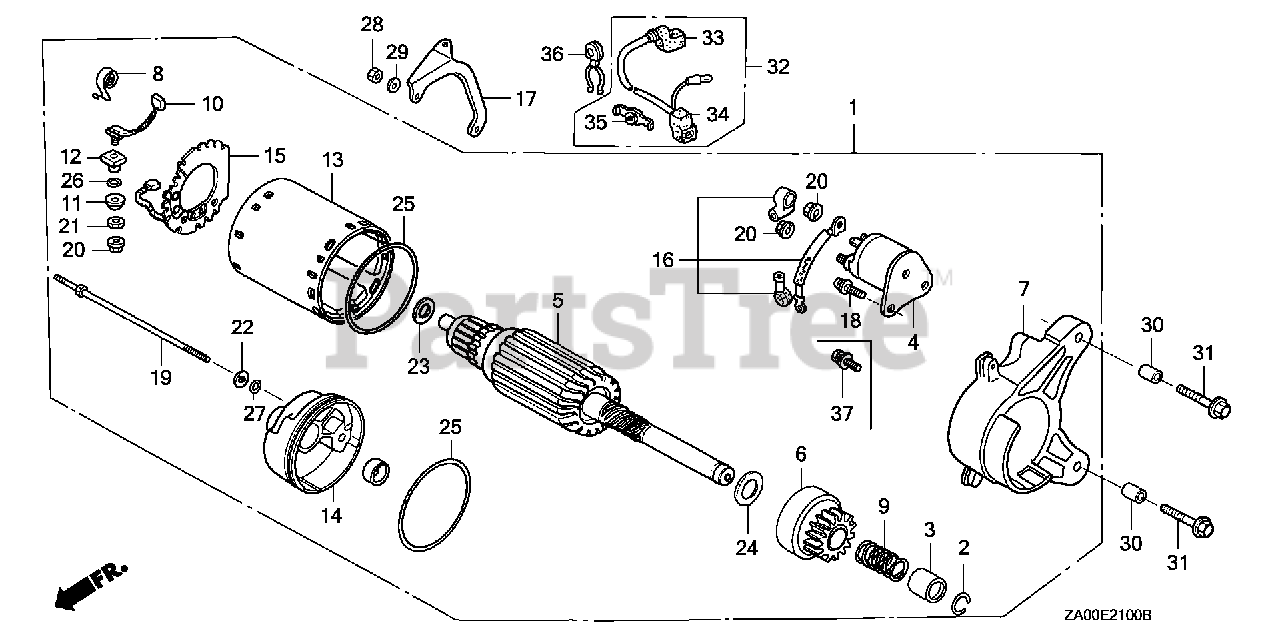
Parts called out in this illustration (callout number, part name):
1	STARTER MOTOR ASSY.
2	RING, SNAP
3	COLLAR, CLUTCH STOP
4	CONTACTOR ASSY.
6	CLUTCH ASSY., OVERRUNNING
7	HOUSING, DRIVE SIDE
8	SPRING, BRUSH
11	BUSH, INSULATION
12	BUSH, INSULATION
14	FRAME, STARTER END
15	PLATE, BRUSH HOLDER
16	WIRE, WATER COVER
17	STAY, STARTER MOTOR
18	SCREW-WASHER (5X14)
19	BOLT, THROUGH
22	WASHER, STEEL PLATE (NOT AVAILABLE)
28	NUT, FLANGE (5MM)
29	WASHER, PLAIN (5MM)
30	PIN, DOWEL (10X16)
31	BOLT, FLANGE (8X40)
